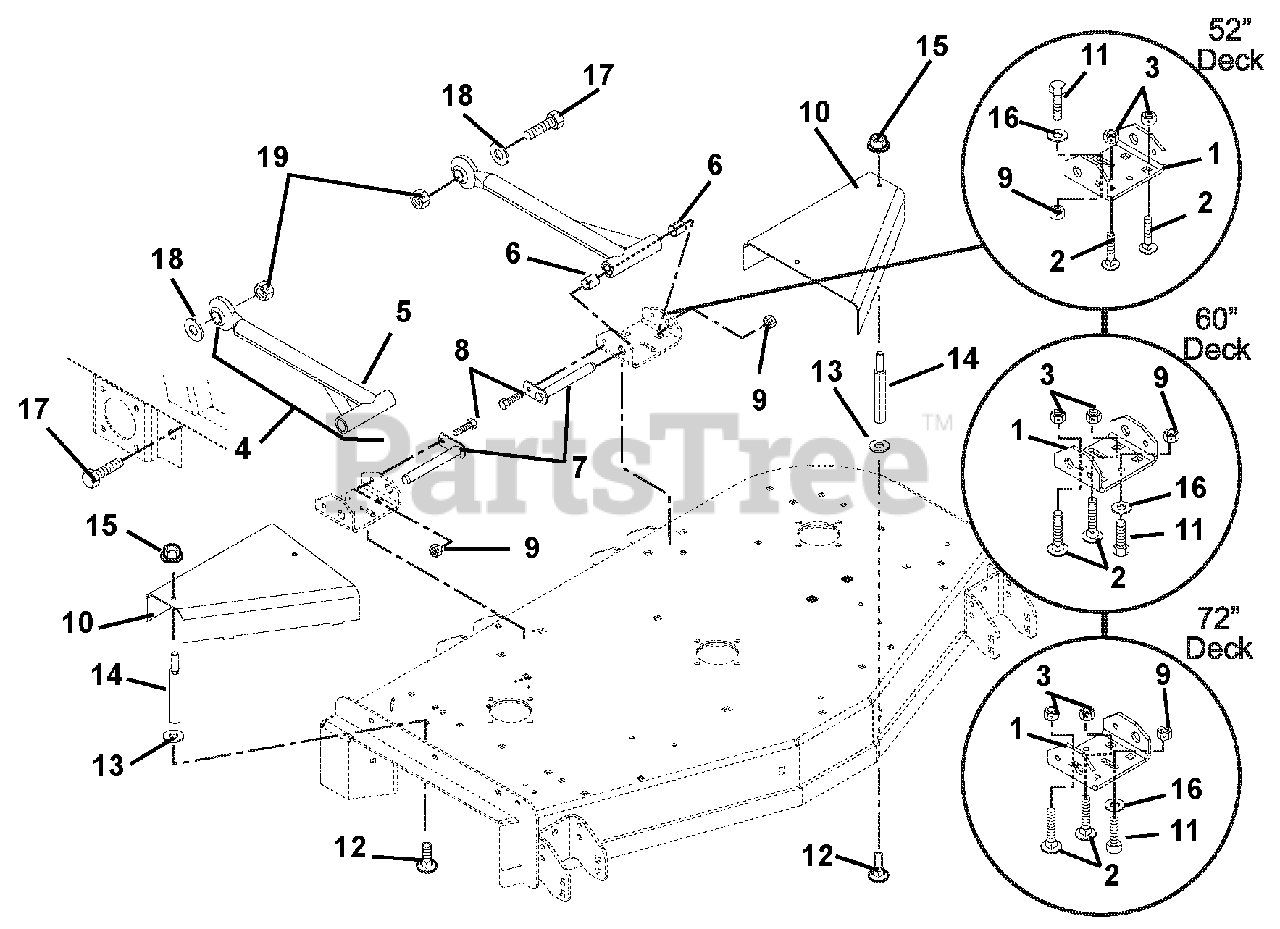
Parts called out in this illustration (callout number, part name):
1	Bracket, Mower Mounting (Rear)
2	Bolt, Round Head Square Neck .50-13 x 1.00 Grade 5
3	Nut, Locking Center Jam .50-13
4	Assembly, Mower Mounting Arm (Includes Items 5 and 6)
5	Weldment, Mower Mounting Arm
6	Bearing .75 x .875 x 1.00
7	Weldment, Mower Mounting Pin
8	Bolt, Hex .38-16 x .88 Grade 5
9	Nut, Locking Top Flange .38-16
10	Guard, Pulley Right Hand (045, 052, 066, 071, 084, 087, 102, 103, 104)
11	Bolt, Hex .38-16 x 1.00 Grade 5
12	Bolt, Round Head Square Neck .31-18 x .75 Grade 5
13	Washer, Flat Steel .38 x .87 x .179 (086, 091, 107, 108)
14	Standoff, 2.75 x .312-18
15	Nut, Locking Top Flange .31-18
16	Washer, Flat Steel .406 x .812 x .065
17	Bolt, Hex .875-9 x 2.75 Grade 5
18	Washer, Flat Steel .875 x 1.50 x .120
19	Nut, Locking Center .875-9
